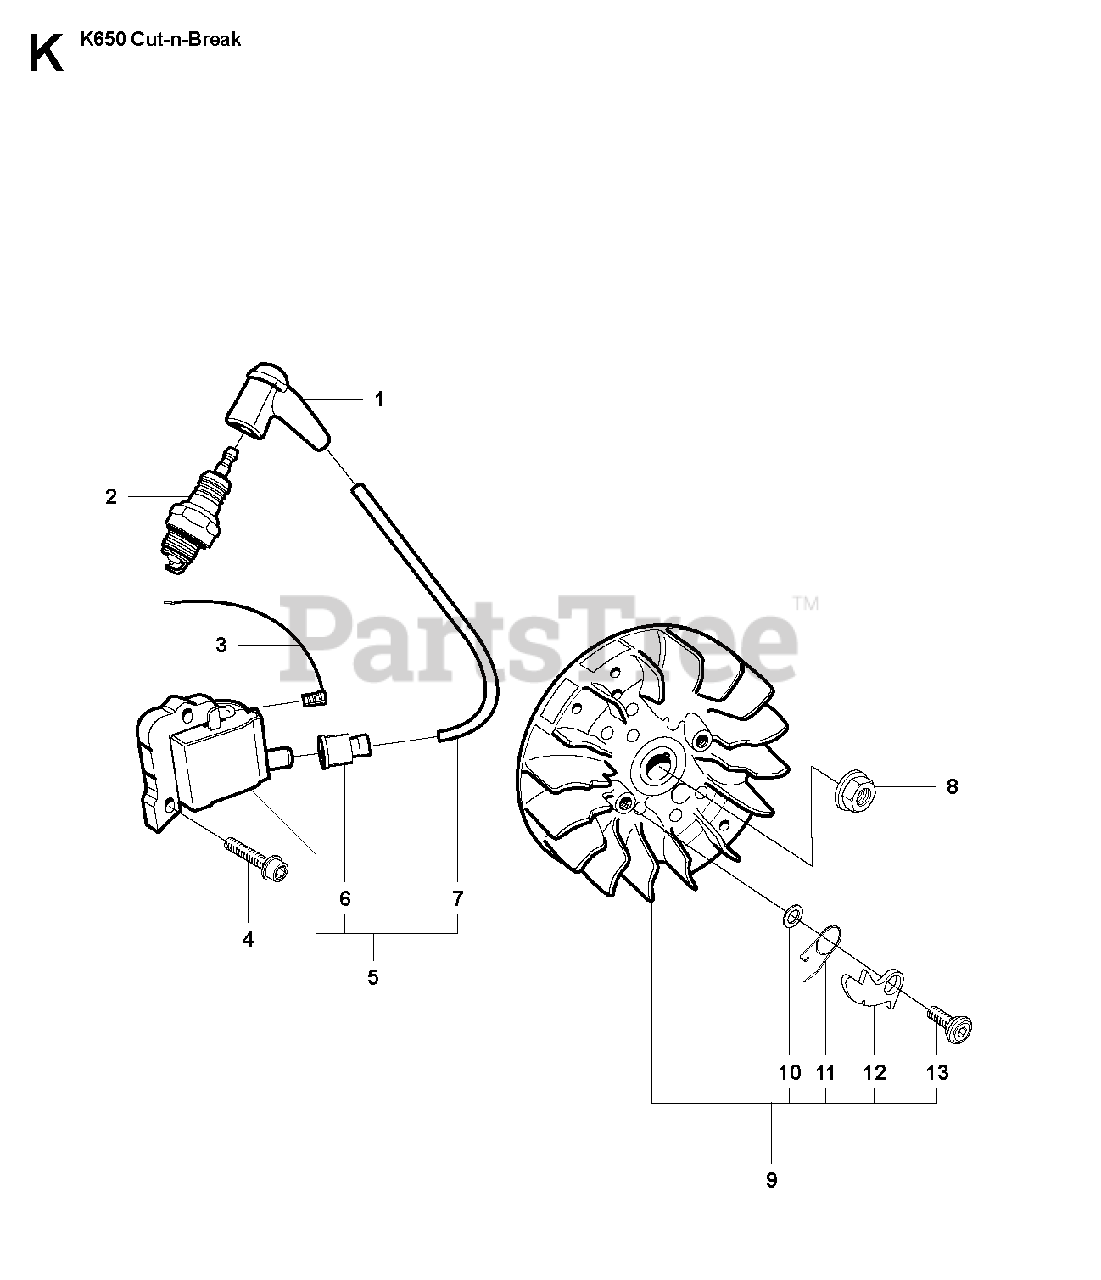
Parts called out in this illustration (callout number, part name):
1	SPARK PLUG CAP
5	IGNITION SYSTEM
7	IGNITION CABLE
